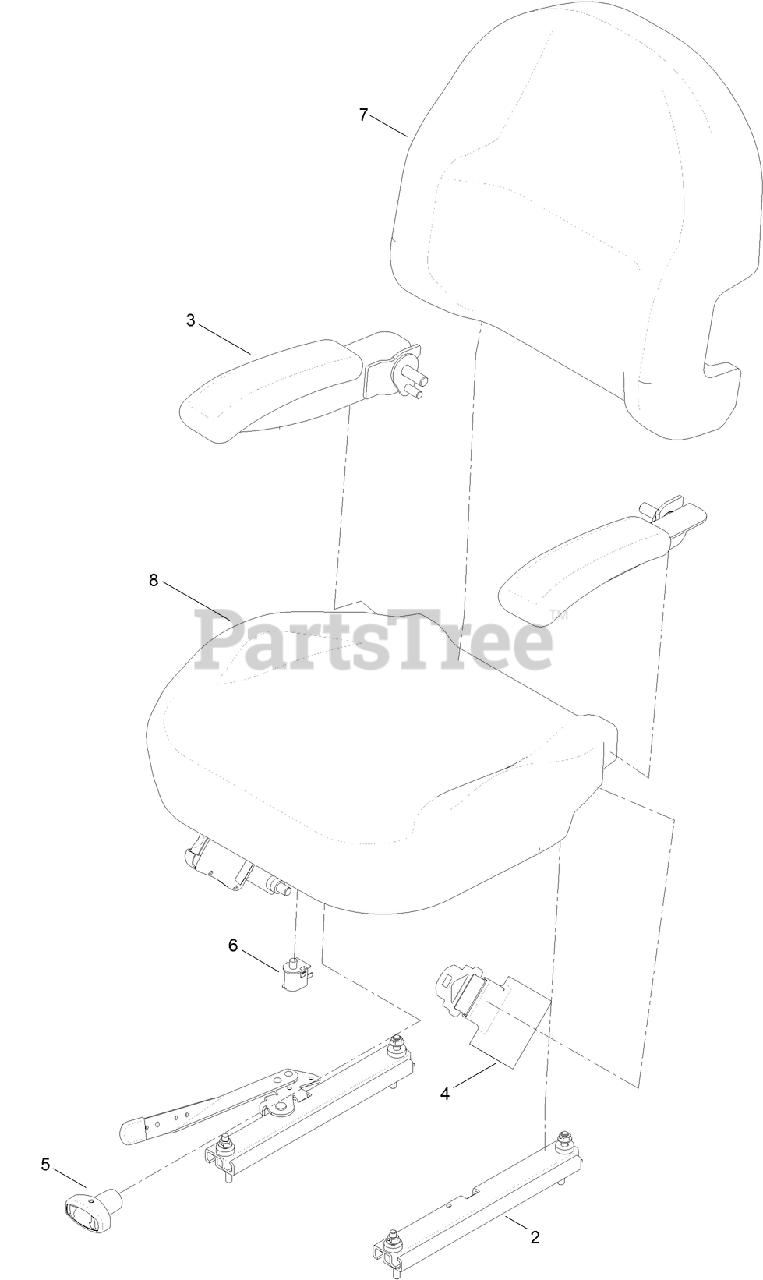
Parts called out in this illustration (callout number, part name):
2	TRACK SET
3	ARMREST KIT
4	SEAT BELT KIT
5	KNOB-ADJUSTER
6	SWITCH-BAIL
7	COVER-BACK
8	COVER-CUSHION
